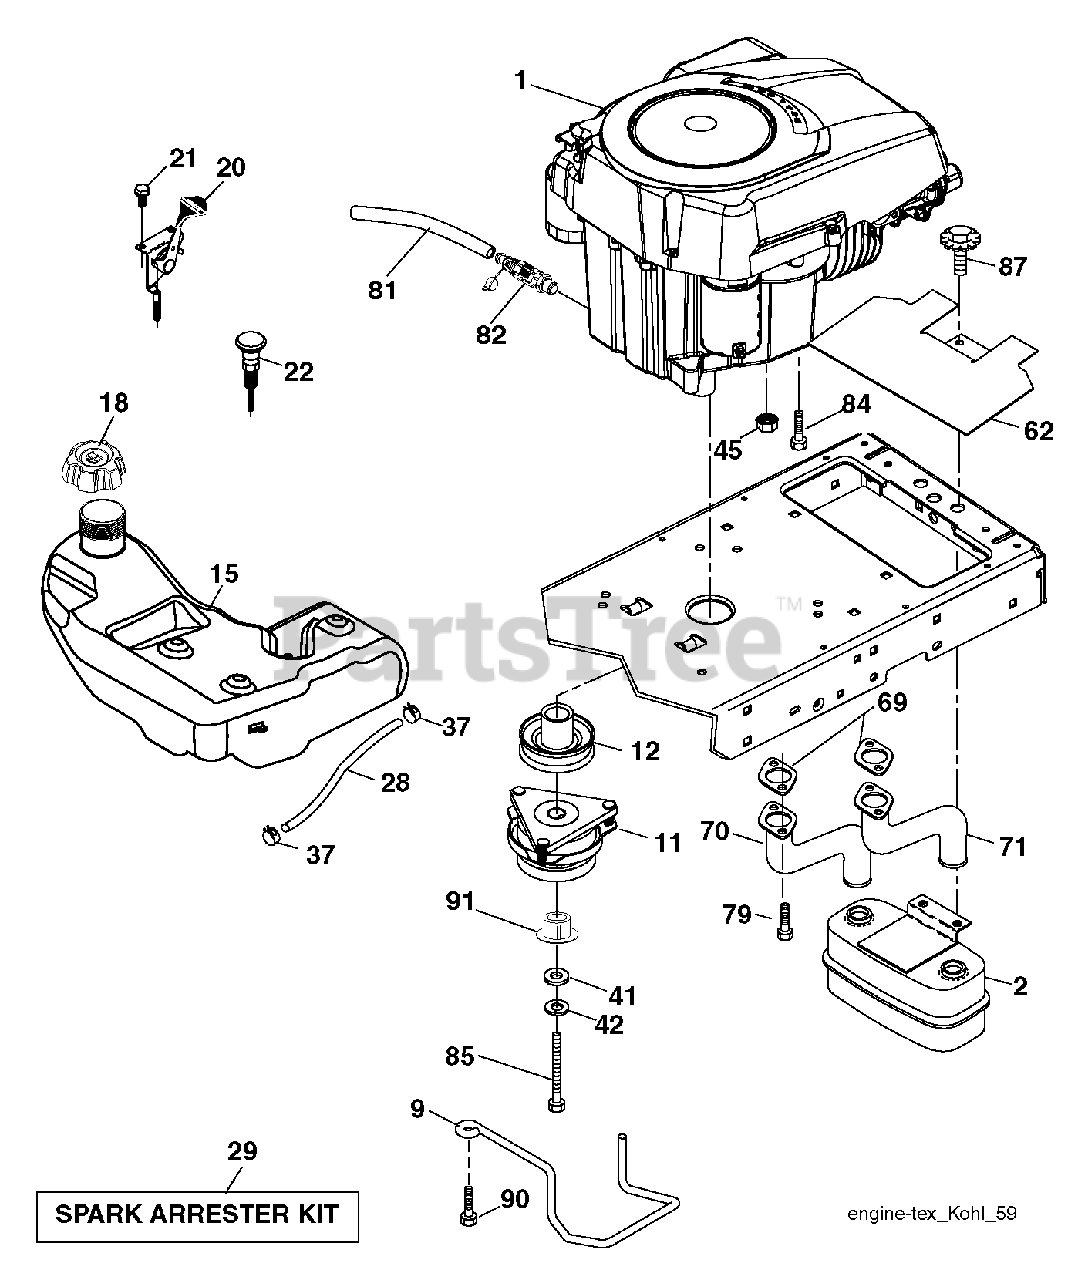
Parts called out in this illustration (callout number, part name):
2	MUFFLER.TWIN.CYL.LOW.TONE
9	KEEPER BELT ENGINE
11	RB.CLUTCH.OGURA.4.4.PD
12	PULLEY.ENGINE.TUFFTORQ
15	TANK.FUEL.4GAL
18	CAP.FL.R.3'N/CARB.H.CROWN.498
20	THROTTLE CONTROL
21	SCREW.#10 X 0.750.BOS
22	CONTROL.CHOKE.ERGO.PUSH-IN.BLA
28	LINE.FUEL.64"REAR.EMIS
29	KIT.SPARK ARRESTOR 794945 B&S
37	HOSE CLAMP
42	LOCKWASHER
45	NUT
62	SHIELD.HEAT.MUFFLER
69	GASKET.EXHAUST.KOHL.CV18-CV26
70	RP.PIPE-EXHAUST LH
71	RP.PIPE-EXHAUST RH
79	SCREW.SOCKET HD.5/16-1
81	TUBE, DRAIN OIL ASM.
82	VALUE.OIL.DRAIN
84	SCREW 3/8-16X1
85	BOLT HEX 7/16-20X4-1/4"
87	BOLT, 5/16-18 X 1 3/4
90	SCREW 3/8-16X1
91	BUSHING.1.375OD
